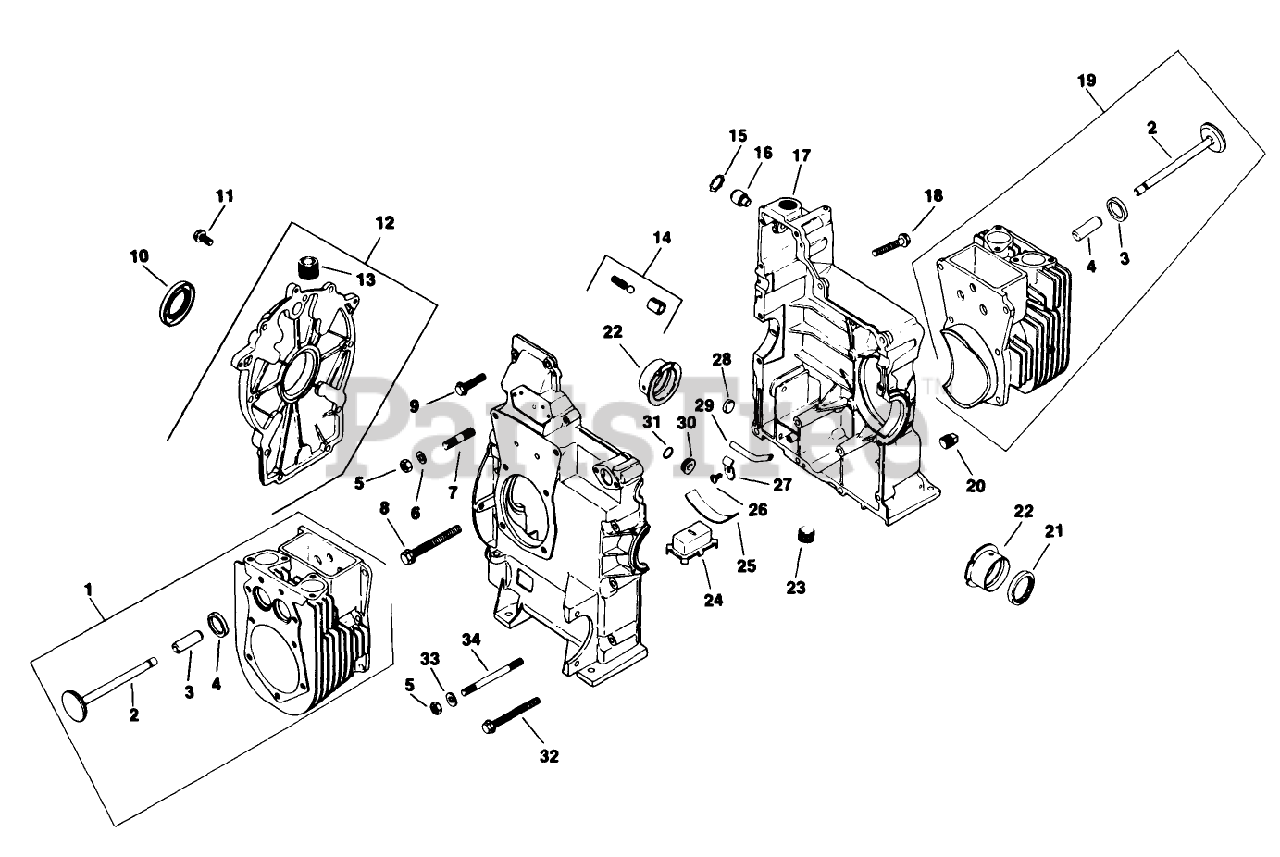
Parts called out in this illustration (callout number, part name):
1	Kit-#2 Cylinder Barrel (Incl. Ref. #2-4)
2	Valve-Exhaust
3	Guide-Valve
4	Inset-Valve Seat
5	Nut
6	Washer-Flat
8	Screw-Hex Flange
9	Screw-Hex Flange
10	Seal-RearOil
11	Screw-Wash Head
12	Kit-Closure Plate (Incl. Ref. #13)
13	Plug
14	Kit-Oil Relief
15	Ring-Retaining
16	Shaft-Governor
18	Screw-Hex Flange
19	Kit-#1 Cylinder Barrel (Incl. Ref. #2-4)
20	Plug
21	Seal-ReAR Oil
22	Bearing-Sleeve .020"
23	Plug-Hex
24	Housing-Oil
25	Clip-Spring
26	Screw
28	Plug-Cup
29	Tube-Oil Pickup
32	Screw-Hex Flange
33	Washer-Flat
34	Stud
